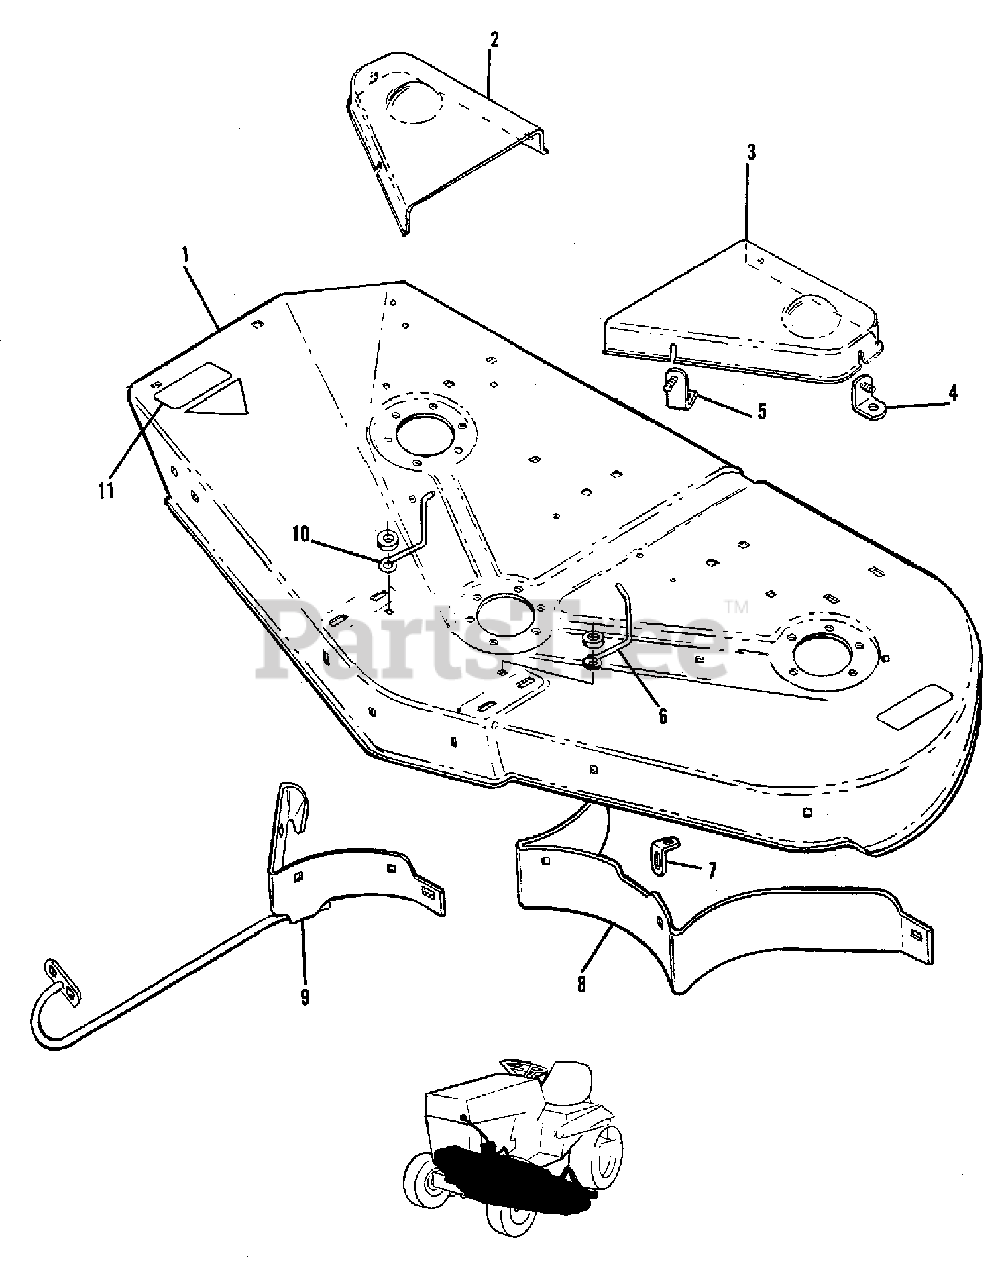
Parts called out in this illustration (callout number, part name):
1	*HOUSING, Main
1	**HOUSING, Main
2	COVER, Arbor, R.H.
3	COVER, Arbor, L.H.
4	LEG ASSEMBLY, Cover Outer
4	CARRIAGE BOLT, 5/16 NC x 3/4
4	WASHER, Plain, 3/8 x 7/8 x #16
4	LOCKWASHER, 5/16
4	NUT, 5/16 NC
4	LOCKWASHER, 1/4
4	NUT, 1/4 NC
4	WASHER, Plain, 9/32 x 5/8 x 1/16 Thickness
5	LEG ASSEMBLY, Cover Inner
5	CARRIAGE BOLT, 5/16 NC x 3/4
5	WASHER, Plain, 3/8 x 7/8 x #16
5	LOCKWASHER, 5/16
5	NUT, 5/16 NC
5	LOCKWASHER, 1/4
5	NUT, 1/4 NC
5	WASHER, Plain, 9/32 x 5/8 x 1/16 Thickness
6	GUIDE, Belt, L.H.
6	CARRIAGE BOLT, 5/16 NC x 3/4
6	WASHER, Plain, 3/8 x 7/8 x #16
6	LOCKWASHER, 5/16
6	NUT, 5/16 NC
7	CLIP, Baffle
7	CARRIAGE BOLT, 1/4 NC x 5/8
7	CAPSCREW, 1/4 NC x 5/8
7	WASHER, Plain, 5/16 x 3/4 x #16
7	LOCKWASHER, 1/4
7	NUT, 1/4 NC
8	**BAFFLE, Housing
8	*BAFFLE, Housing
8	CARRIAGE BOLT, 3/8 NC x 3/4
8	**CARRIAGE BOLT, 3/8 NC x 1
8	LOCKWASHER , 3/8
8	NUT, 3/8NC
9	**GUARD ASSEMBLY, Discharge
9	*GUARD ASSEMBLY, Discharge
9	CARRIAGE BOLT, 5/16 NC x 3/4
9	CARRIAGE BOLT, 3/8 NC x 3/4
9	LOCKWASHER, 5/16
9	LOCKWASHER, 3/8
9	NUT, 5/16 NC
9	NUT, 3/8NC
10	GUIDE, Belt, R.H.
10	CARRIAGE BOLT, 5/16 NC x 3/4
10	WASHER, Plain, 3/8 x 7/8 x #16
10	LOCKWASHER, 5/16
10	NUT, 5/16 NC
11	TRANSFER (Caution)
